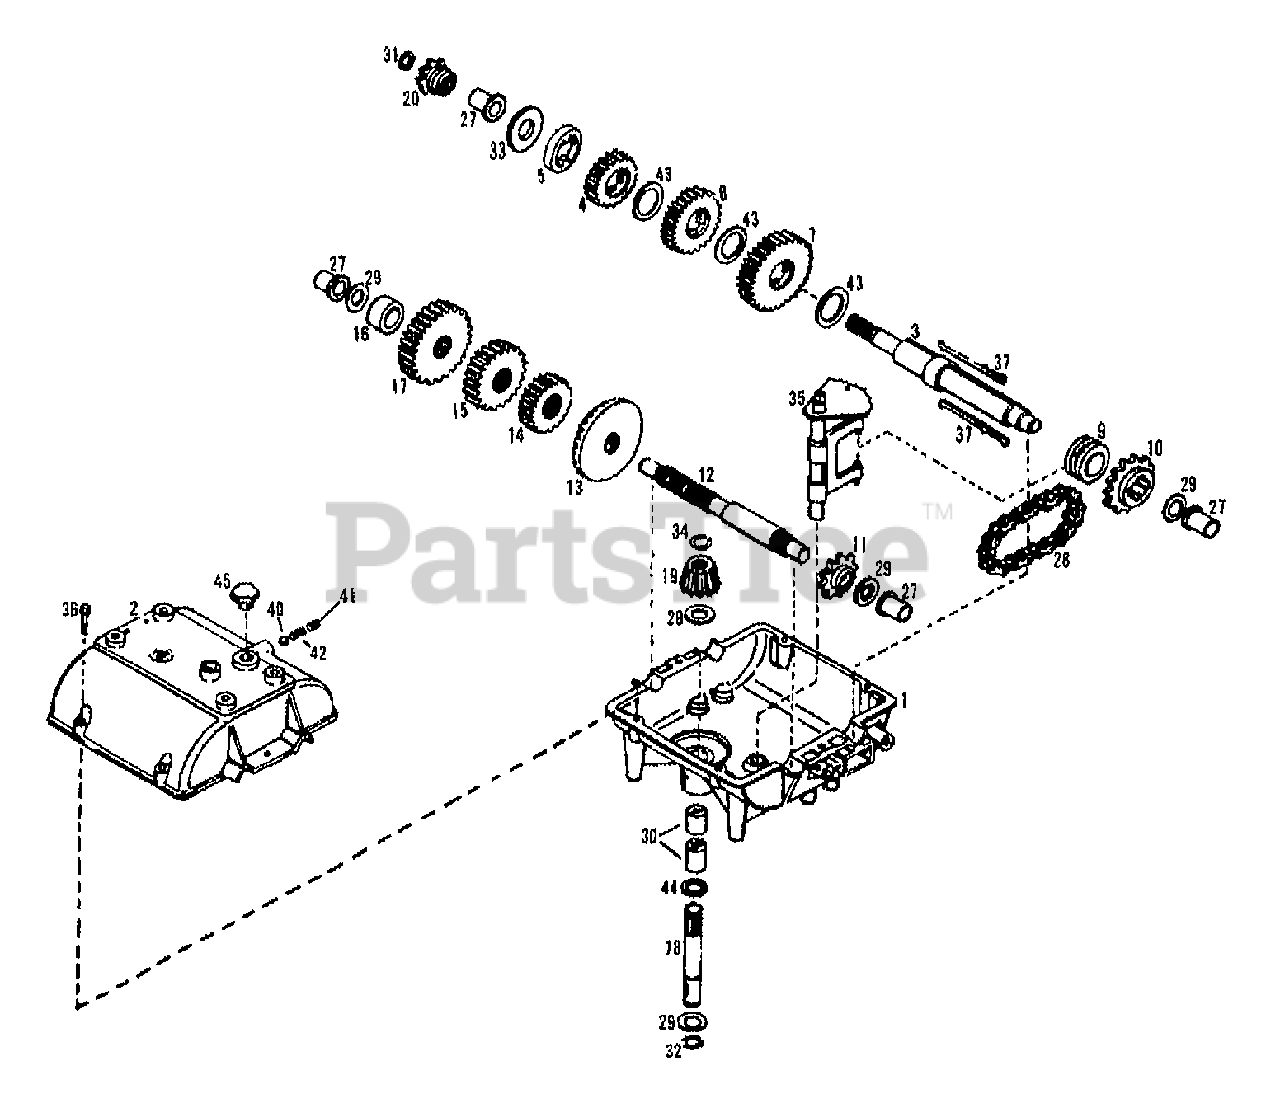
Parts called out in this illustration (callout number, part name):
1	TRANSMISSION CASE
3	OUTPUT SHAFT
4	SPUR GEAR
6	SPUR GEAR
7	SPUR GEAR
10	SPROCKET
11	SPROCKET
12	COUNTERSHAFT
13	BEVEL GEAR
14	SPUR GEAR
15	SPUR GEAR
17	SPUR GEAR
18	INPUT SHAFT
19	INPUT PINION
20	SPROCKET
27	BUSHING
28	ROLLER CHAIN
29	WASHER
30	NEEDLE BEARING
31	RET RING
32	RET RING
34	RET RING
35	ROD & FORK
37	SHIFT KEY
42	SPRING
43	WASHER
44	O RING
